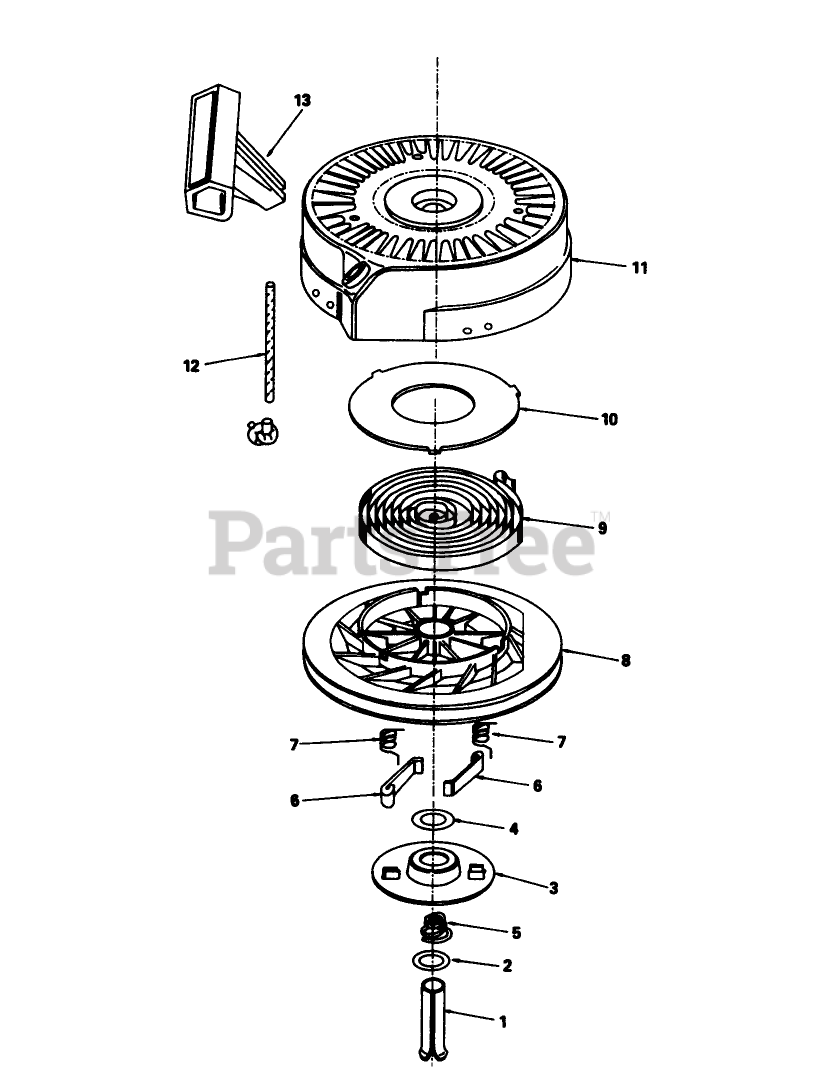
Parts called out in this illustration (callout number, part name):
1	Pin, Spring (Incl. Ref. #7)
2	Washer
3	Retainer
4	Washer
5	Brake Spring
6	Dog-Starter
7	Spring-Dog
8	Pulley
9	Rewind Spring
10	Cover-Spring
11	Housing-Starter
12	Rope-Starter (98 cut to length)
13	Handle-Starter
